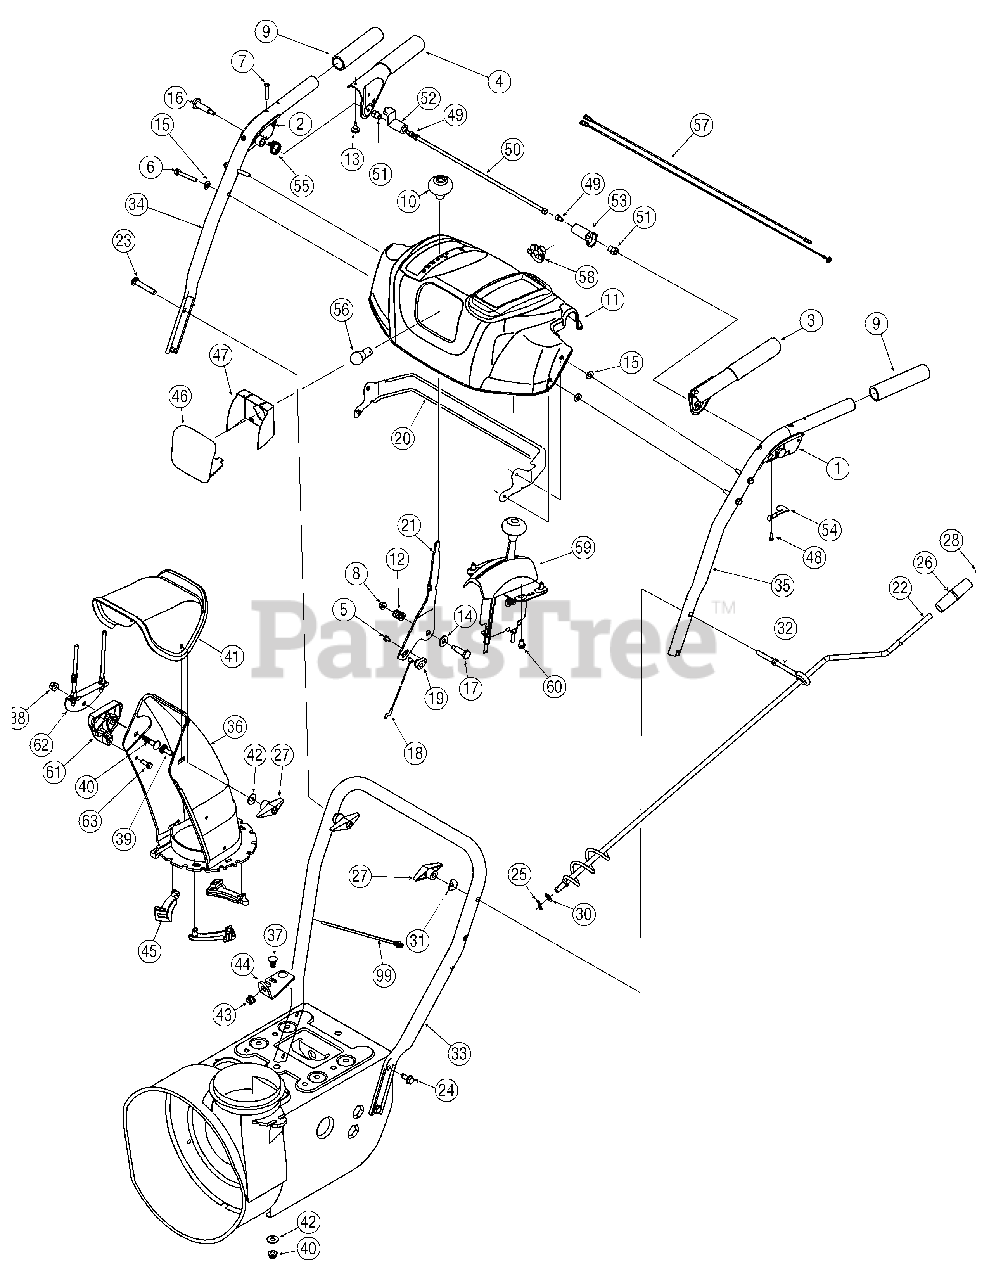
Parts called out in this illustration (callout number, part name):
1	Handle Assembly, Lock, LH
2	Handle Assembly, Lock, RH
3	Handle Ass’ y, Engagement LH
4	Handle Ass’y, Engagement, RH
5	Screw, #10-16, 0.500
6	Screw, 1/4-20, 1.750
7	Screw, Machine, #10-24, 1.375
8	Nut, Flange Lock, 1/4-20, Nylon
9	Grip, 1.0 ID x 5.0
10	Knob, Shift
11	Handle Panel, Yellow, K/L - Style
11	Handle Panel, Gray, K/L -Style
12	Spring, .39 x .60 x .88
13	Bumper, Rubber, .62 OD x .22
14	Washer, Flat, .385 x .870 x .092
15	Washer, Flat, .25 x .630 x .0515
16	Screw, Shoulder, .43 x 1.34, 1/4-20
17	Screw, Shoulder, .374 Dia. X 1.05
18	Cable, Speed Selector
19	Barrel Holder, Cable, LH
23	Screw, Carriage, 5/16-18, 2.25
24	Screw, 5/16-18, 0.75, Gr5
25	Pin, Cotter, .072 x 1.13
26	Crank Knob, 1.0 Dia. x 3.2, Black
27	Knob Assembly, Wing Nut, 5/16-18
28	Cap, Push, 3/8 Rod
29	Grommet, .44 ID x .94 OD x .50
30	Washer, Flat, .375 x .738 x .063
31	Washer, Saddle, 320 x .93 x .060
32	Eye Bolt, Chute Crank
36	Chute, Lower, 5.0 Diameter
37	Bolt, Carriage, 5/16-18, 1.0
38	Nut, Flange Lock, 5/16-18, Nylon
39	Bolt, Carriage, 5/16-18, 1.0
40	Bolt, Carriage, 5/16-18, .750
41	Chute, Upper, w/ Label
42	Washer.349 ID x .879 OD x .063
43	Bushing, Plastic, .380
45	Flange Keeper, Chute
47	Reflector Label, Lens
48	Screw, #8-16 x 0.50
49	Screw, 1/4-20 x.375
50	Pivot Rod
51	Shoulder Nut, 1/4-20
52	Lock Plate
53	Clutch Lock Cam
54	Clutch Lock Spring
55	Torsion Spring
56	Lamp
57	Wire Harness
58	Light Socket
59	Chute Control Ass’y, Two-Way
60	Screw, 1/4-15, 0.50
61	Cable Guide, Chute Tilt
63	Screw, 1/4-15, 0.750
